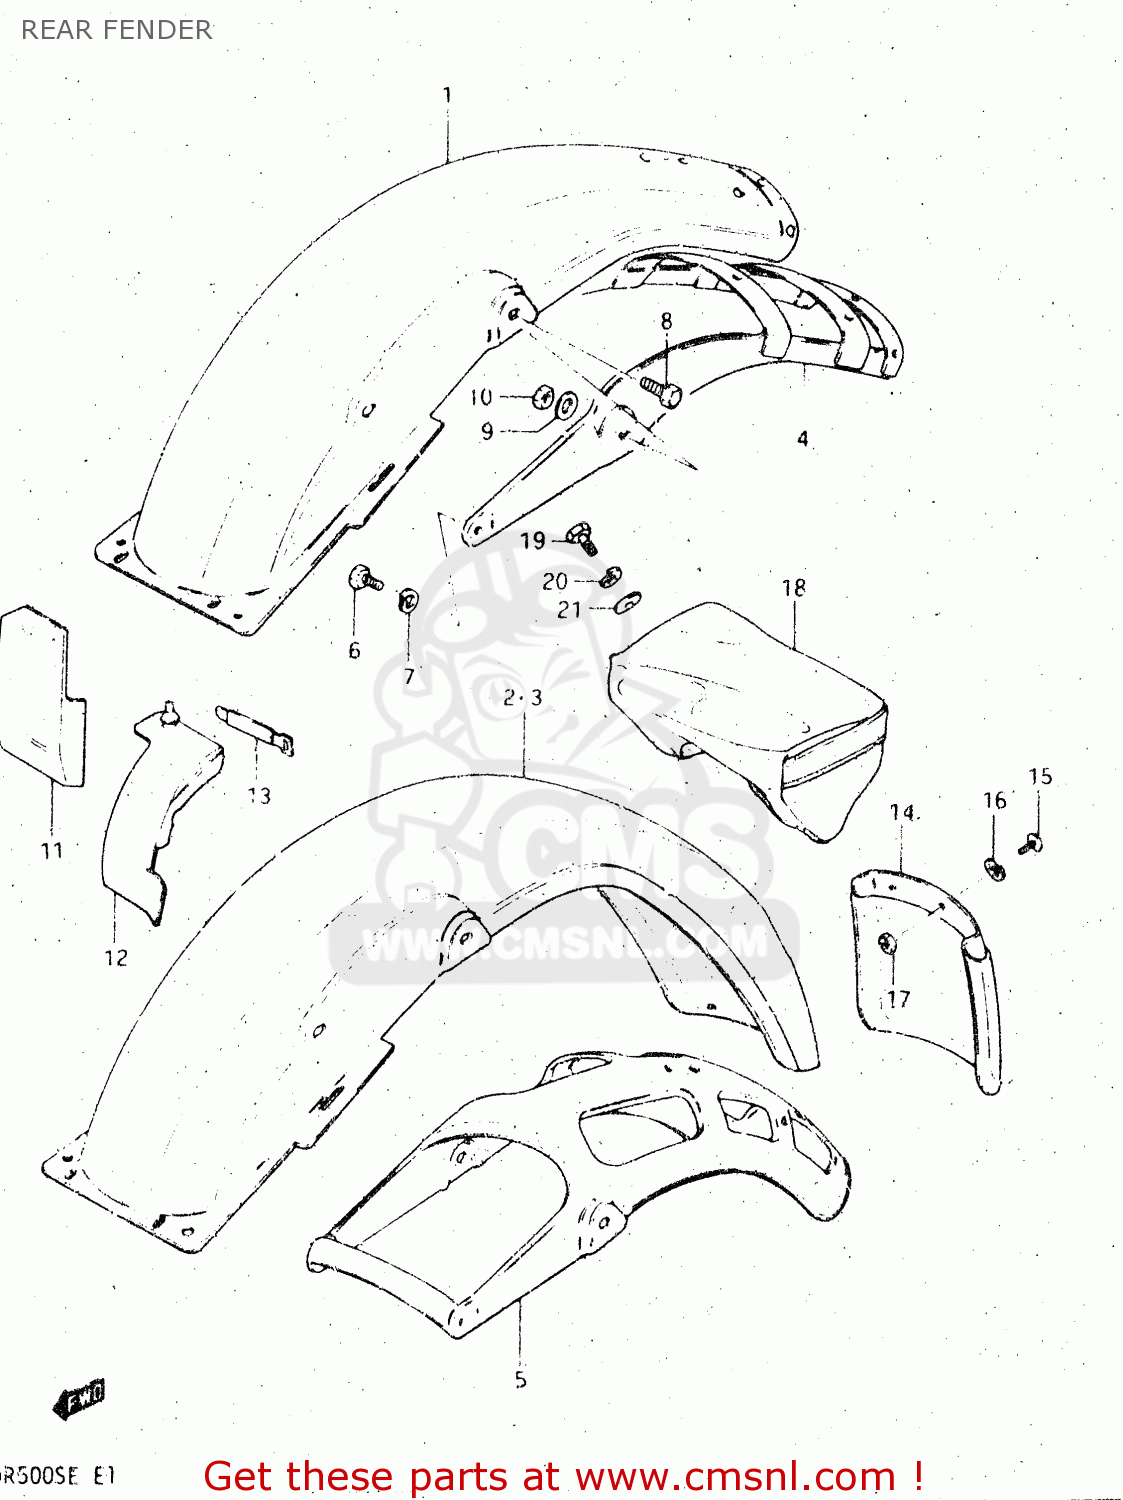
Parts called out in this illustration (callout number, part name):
1	FENDER, REAR (BLUE)
2	FENDER, REAR (RED)
3	FENDER, REAR (RED)
4	REINFORCEMENT,REAR FENDER
5	REINFORCEMENT
6	BOLT,8X1.25X2
7	WASHER,LOCK,8.
8	BOLT (8X30)
9	WASHER
10	NUT
11	MUD GUARD,REAR FENDER
12	MUD GUARD,REAR FENDER
13	CLAMP L:110
14	EXTENSION, REAR FENDER
15	SCREW
16	LOCK WASHER
17	NUT
18	BAG (SUPER BLUE)
19	BOLT
20	LOCK WASHER
21	WASHER
